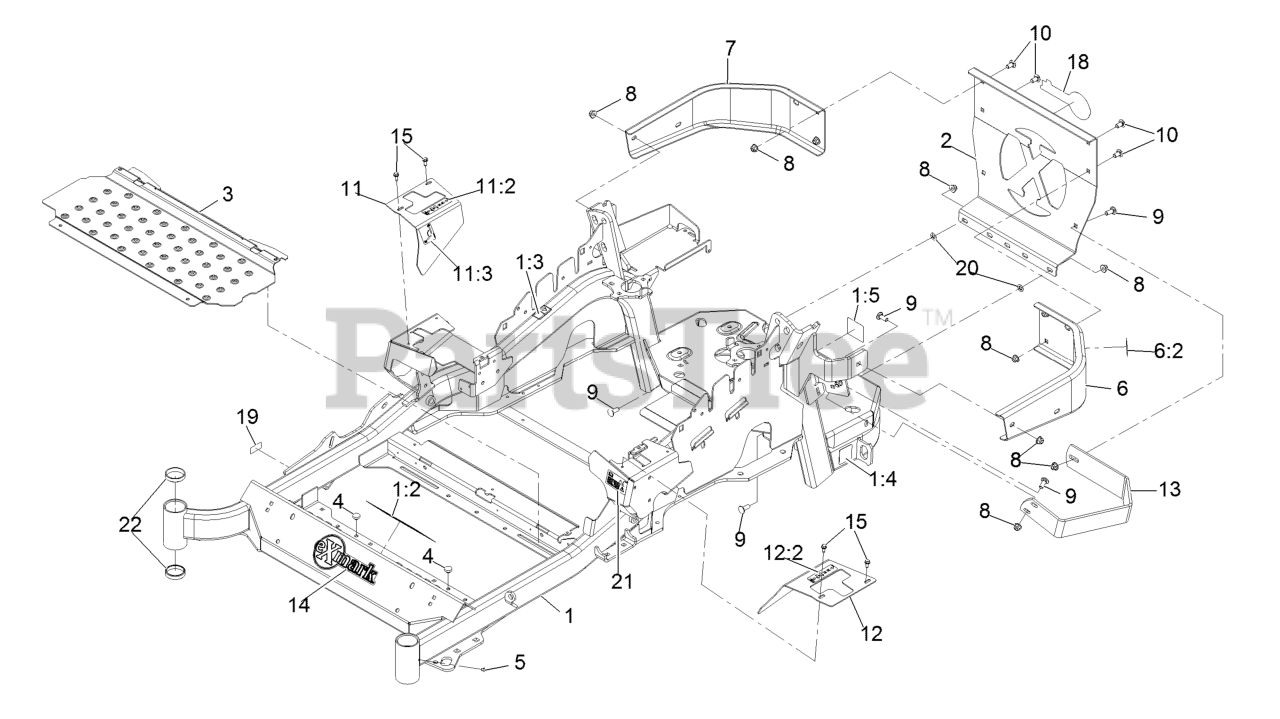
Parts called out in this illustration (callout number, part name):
1	MAINFRAME ASM
1:2	DECAL-DANGER
1:3	DECAL-WARNING
1:4	DECAL-HAZARD, PINCHED FINGER
1:5	DECAL-SPARK ARRESTER
2	PLATE,REAR GUARD
6	LH BUMPER ASM
6:2	DECAL-WARNING
7	BUMPER-RH
8	NUT-HF, NI
9	SCREW-CARR
10	SCREW-CARR
11	RH MOTION CONTROL COVER ASM
11:2	DECAL-CONTROL, MOTION
11:3	DECAL-PARK BRAKE, CE
12	LH MOTION CONTROL COVER ASM
12:2	DECAL-CONTROL, MOTION
13	GUARD-MUFFLER
14	DECAL-EXMARK LOGO
15	SCREW-HWH
18	DECAL-EXMARK LOGO
19	Decal-Patent
20	NUT-PUSH
21	DECAL-FUEL FILL, CE
22	CUP-BEARING
